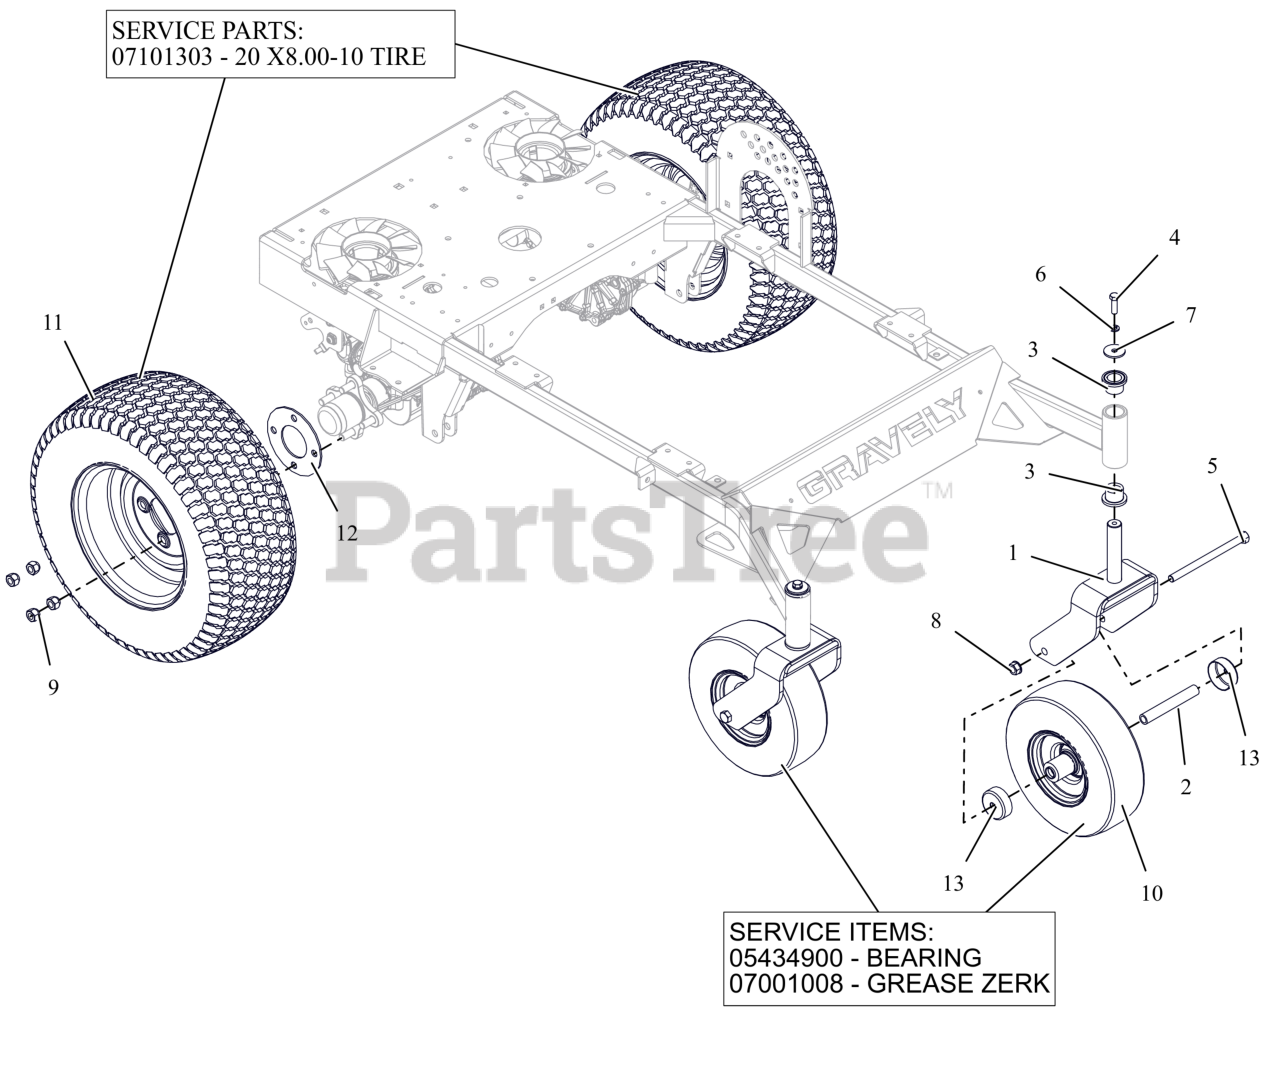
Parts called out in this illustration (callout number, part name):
1	WLDMT, CASTER FORK (RED)
2	SPACER, ROLLED WHEEL
3	BRG, FLG 1.00 X 1.25 X 1.00
4	BLT, HEX .38-16X1.25 G5 ZCC
5	BLT, HEX 0.5-13X7 GR5 ZCC
6	WSHR,LK-REG .375X.094 ZCC
7	WSHR, FLT .380X1.50X.125 ZCC
8	NUT-LK-CTR-FLG .500-13 GG ZCC
9	NUT, WHEEL .50-20 ZCC
10	ASM, WHL/TIRE 11X4.00-5
10	BRG-BALL .752X1.380X.500
10	GREASE FITTING 1/4-28 EXTENDED
10	TUBE 11 X4.0-5 TR87
11	ASM, WHL/TIRE 20X8.00-10
11	20 X 8.00-10 TIRE
11	TUBE, 20X10-10
12	SPACER, WHEEL 4-BOLT
13	SHIELD, WHEEL BEARING
